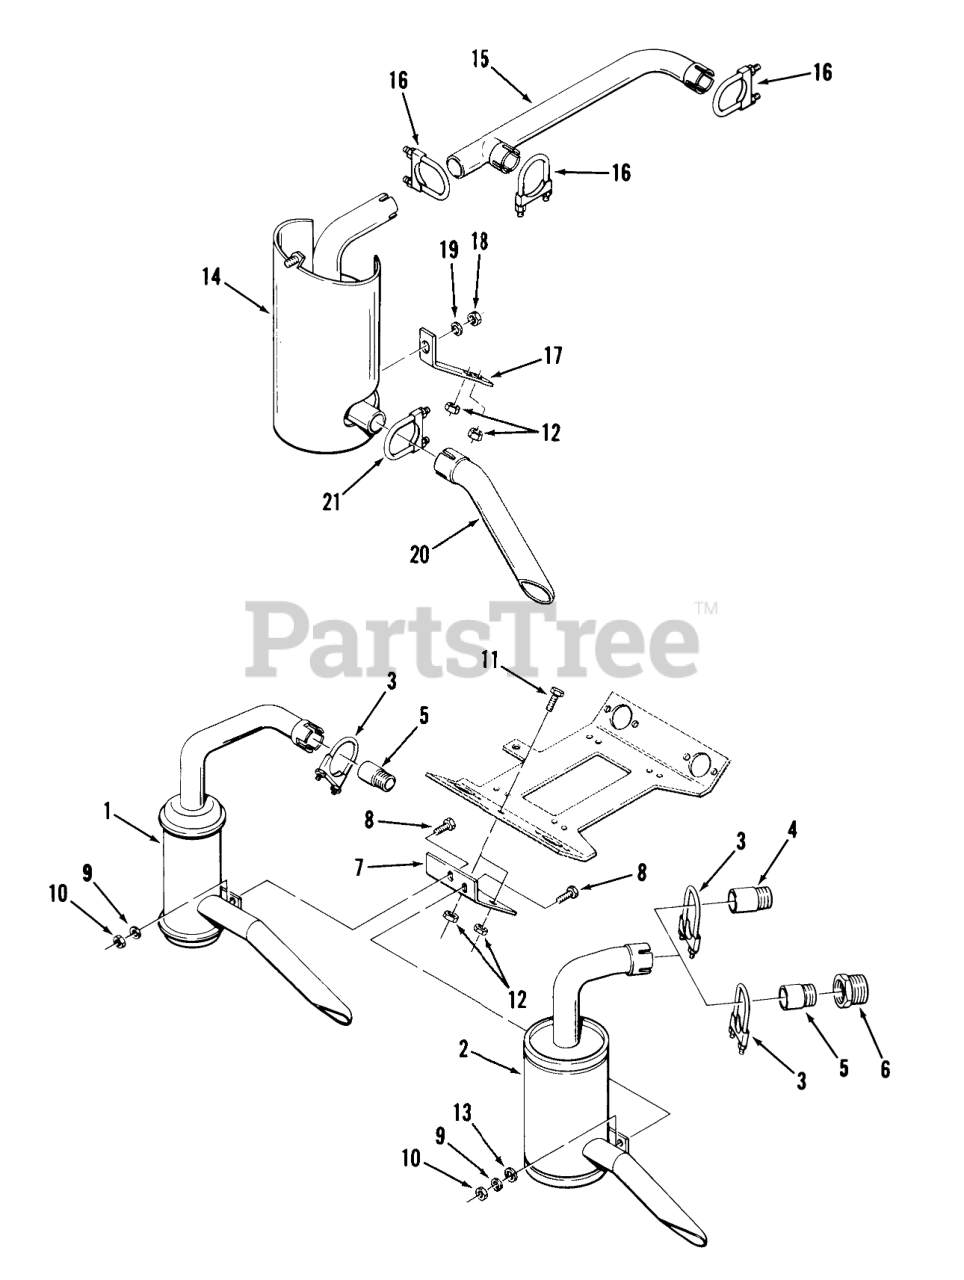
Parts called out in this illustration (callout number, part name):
1	ASSY-MUFFLER
2	MUFFLER ASSEMBLY
3	ASSY-MUFFLER CLAMP
4	NIPPLE
5	NIPPLE- 1X2 SPECIAL
6	REDUCER 1 1/4-1
7	BRACKET-MUFFLER MTG
8	H H C S
9	Washer
10	Nut
11	Bolt
12	Nut
14	Muffler C-175 Twin Only
15	MANIFOLD-EXHAUST
16	CLAMP-1 1/2
17	Muffler Mounting Bracket C-175 Twin Only
18	Nut
19	LOCKWASHER
20	Muffler Extension C-175 Twin Only
21	ASSY-MUFFLER CLAMP
